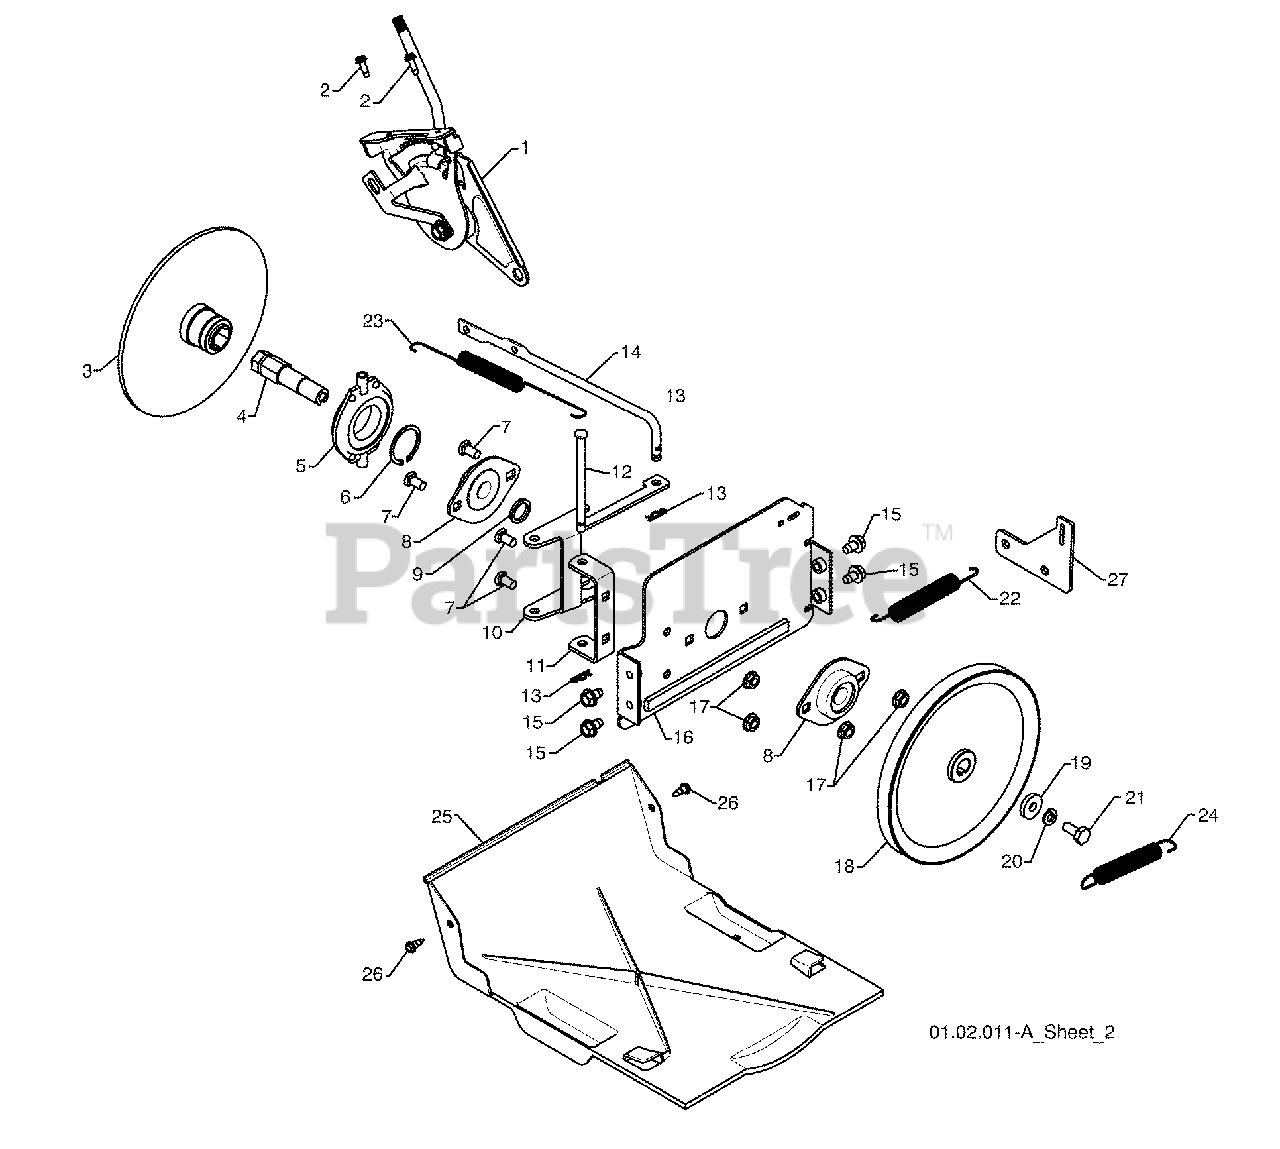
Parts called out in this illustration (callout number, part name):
1	SPEED SELECTOR HEAD ASSEMBLY
2	SCREW 10-24 X .625
3	DRIVE PLATE WELDMENT
5	TRUNNION BEARING ASSEMBLY
6	RETAINER
7	CARRIAGE BOLT 5/16-18 X .625
8	FLANGE BEARING
10	LEVER SHIFTER PLATE
11	SHIFTER SUPPORT BRACKET
14	CLUTCH ROD
15	BOLT 5/16-18 X .500
16	DRIVE MOUNT PLATE
17	NUT 5/16-18
18	TRACTION PULLEY
20	LOCKWASHER 5/16
21	SCREW 5/16-18 X .750
22	TRACTION SPRING
23	RETURN SPRING
24	BRAKE SPRING
25	BOTTOM PAN
26	SCREW 10-24 X .625
27	TRACTION SPRING BRACKET
